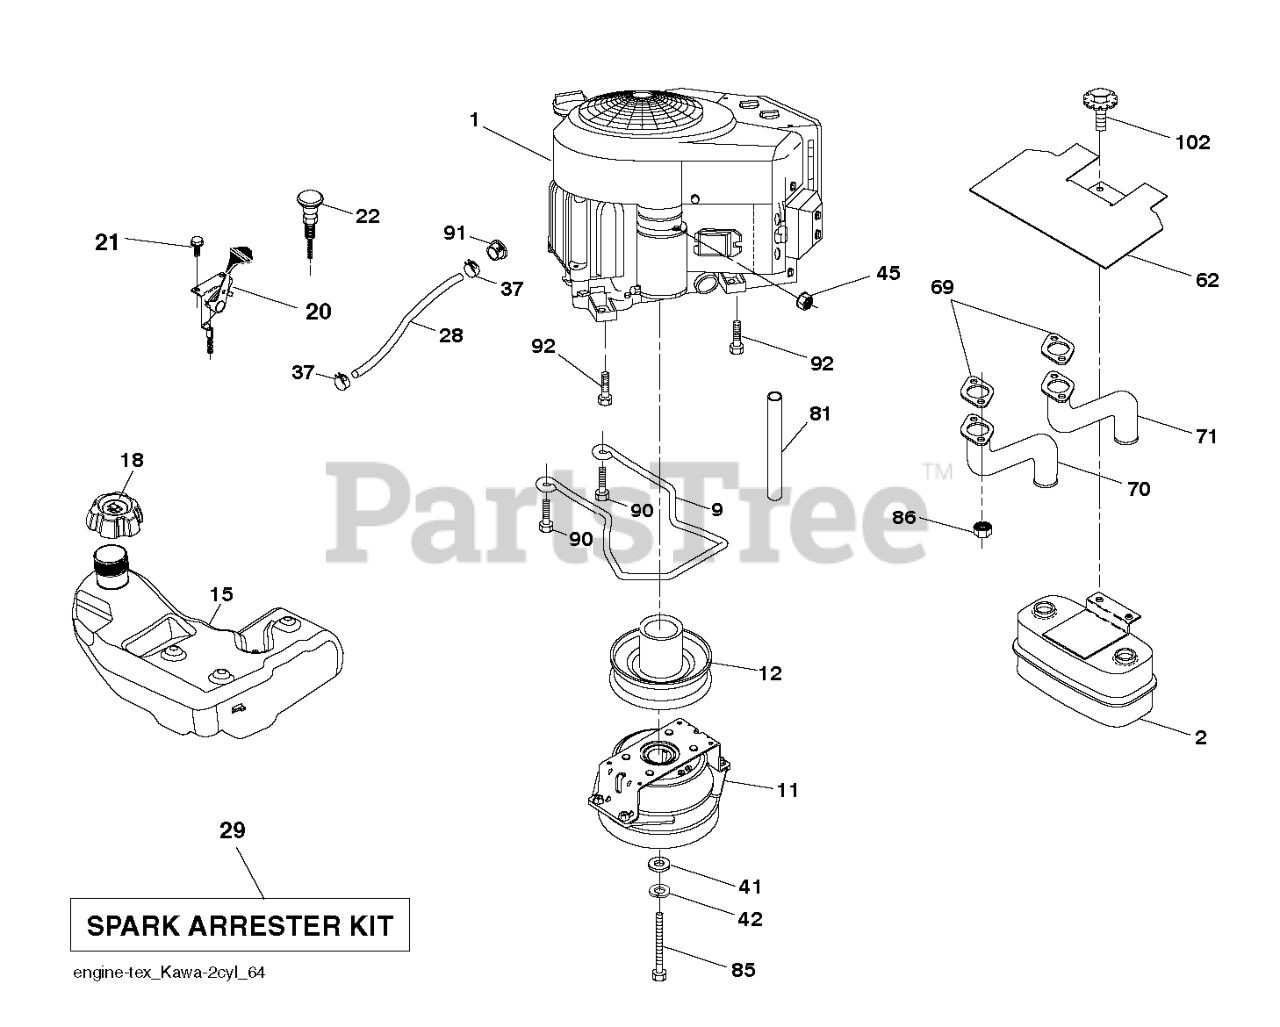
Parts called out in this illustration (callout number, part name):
2	MUFFLER.ASM.TWIN.MNTG.BRACKET
9	KEEPER.BELT.ENG.4.25"2.BLT.431
11	CLUTCH.OGURA.4.4PD.GT1.5-EH13V
12	PULLEY.ENGINE.TUFFTORQ
15	FUEL.TANK.ASM.3.0GAL.REAR.2019
18	CAP ASSY FUEL 3" GRAY
18	FUEL CAP
20	CONTROL.THROTTLE.COBRA.BLACK
22	CONTROL, CHOKE
28	HOSE.1/4".LOW.PERM.FUEL.LN.60"
29	KIT.SPARK ARRESTOR 794945 B&S
37	HOSE CLAMP
62	SHIELD.HEAT.MUFFLER
70	TUBE.EXHAUST.LH.FR961/FR730
71	TUBE.EXHAUST.RH.FR961/FR730
81	TUBE, DRAIN OIL ASM.
85	CLUTCH BOLT7/16-20X3.5 GR524HR
86	NUT.HEX.FLANGE.TOPLOCK
90	SCREW 3/8-16X1
91	BUSHING.1.375OD
92	SCREW 3/8-16X1
102	SCREW
